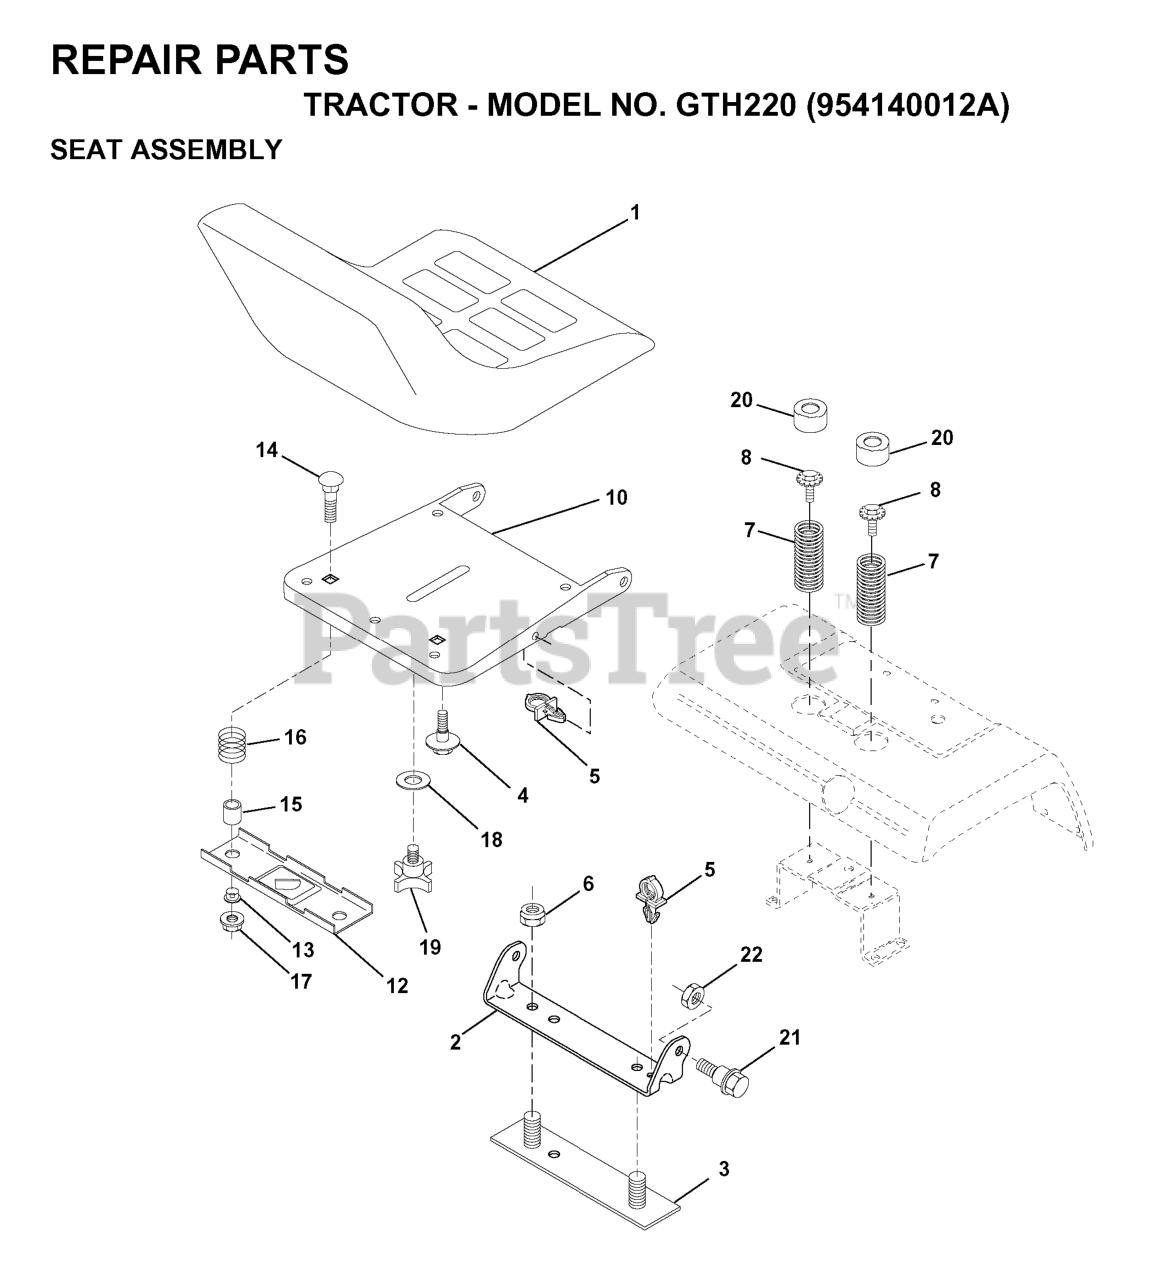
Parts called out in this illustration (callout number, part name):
1	SEAT
2	SEAT PIVOT BRKT
3	STRAP
4	BOLT,SHOULD
6	NUT
7	SPRING COMPRESSION
8	BOLT HEX WASHER HD 5/16-18
10	PAN, SEAT
12	BRKT SWITCH
14	Bolt Rdhd. Sht. Nk 1/4-20 x 1-3/8
15	SPACER SPLIT
16	SPRING COMPRESSED
17	NUT T
19	KNOB 1/2" YT
20	CAP SPRING
21	BOLT SHOULDER 5/16-18
22	LOCKNUT
